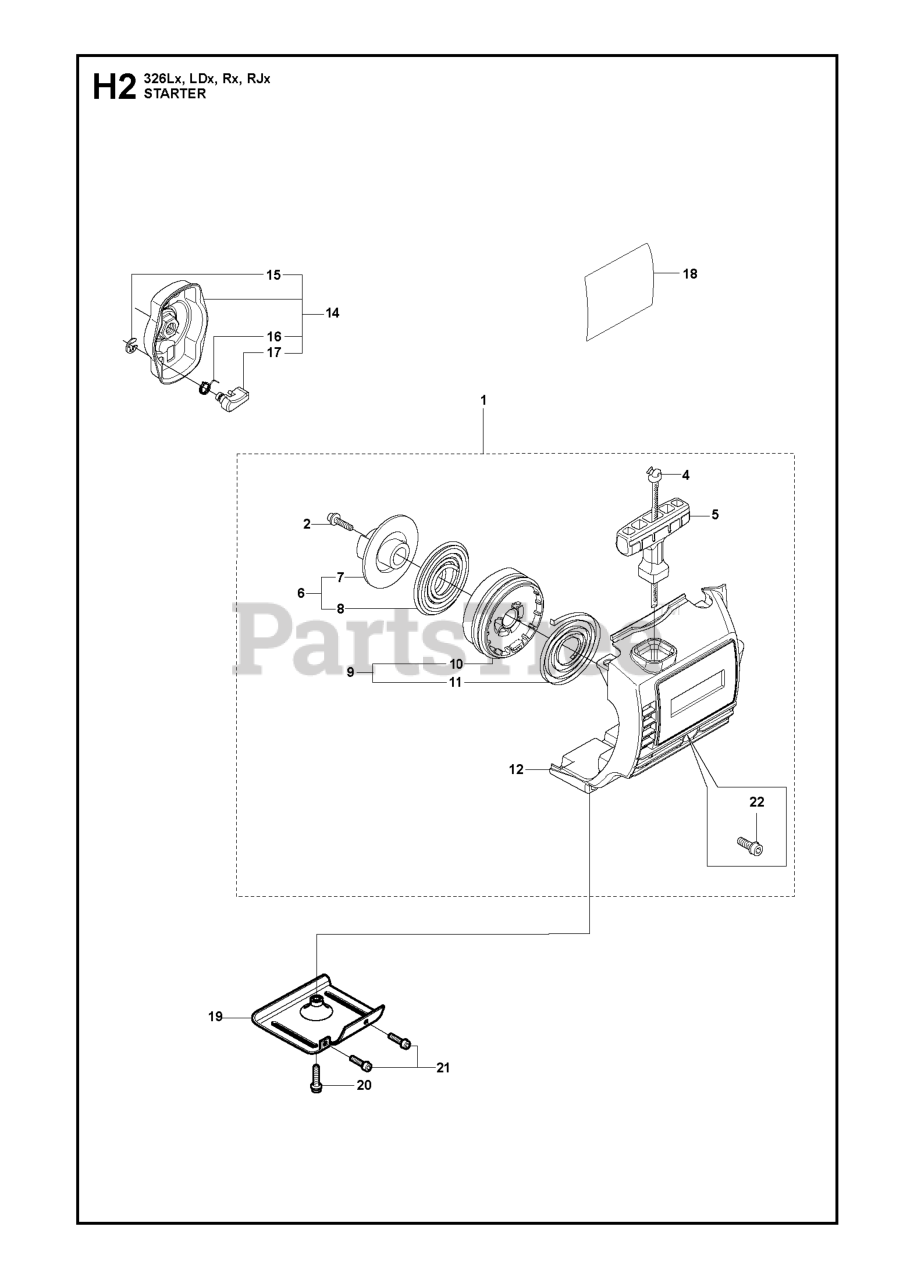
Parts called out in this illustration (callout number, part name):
1	STARTER ASSY
4	STARTER ROPE
5	STARTER HANDLE
7	DRIVER PULLEY
8	SPRING - DRIVER
9	STARTER PULLEY
10	STARTER PULLEY
12	STARTER HOUSING
14	STARTER PAWL BRIDGE
17	STARTER PAWL
18	DECAL DEVICE
18	DECAL
18	DECAL, STARTER HOUSING
22	SCREW IHSCFMO
